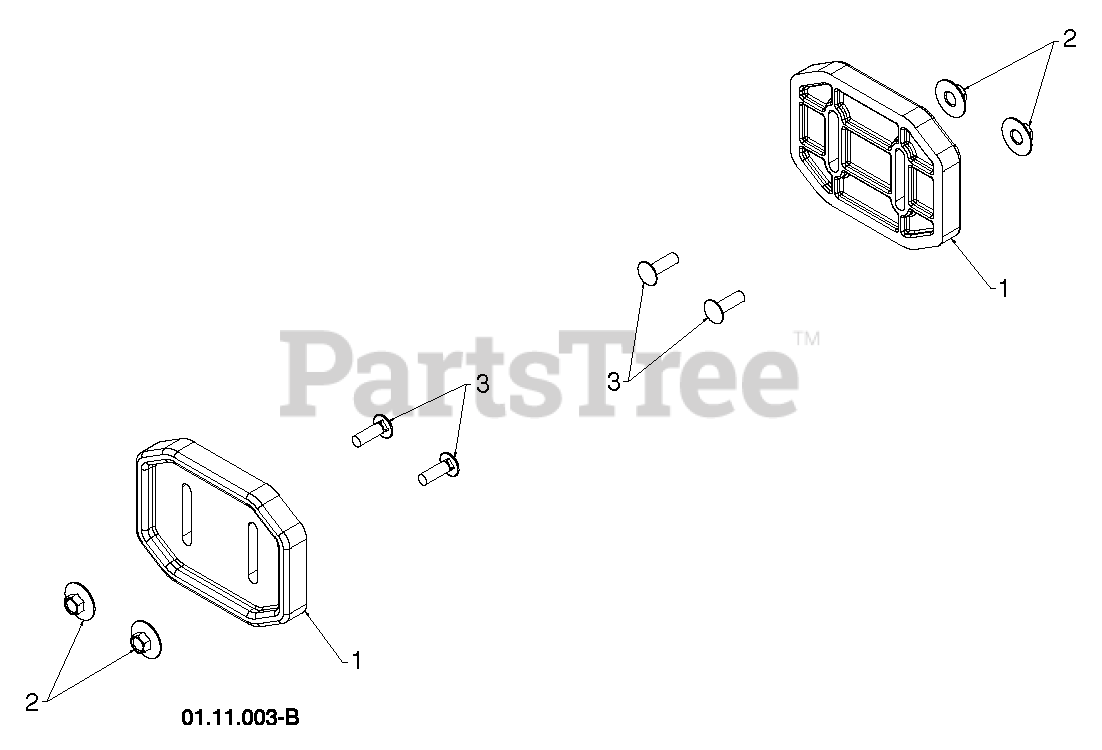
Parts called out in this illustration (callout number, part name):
1	SKID.PLATE.PLASTIC.
2	NUT.FLANGE.HEX.5/16X18.BLACK
3	BOLT.CARRIAGE.5/16-18
